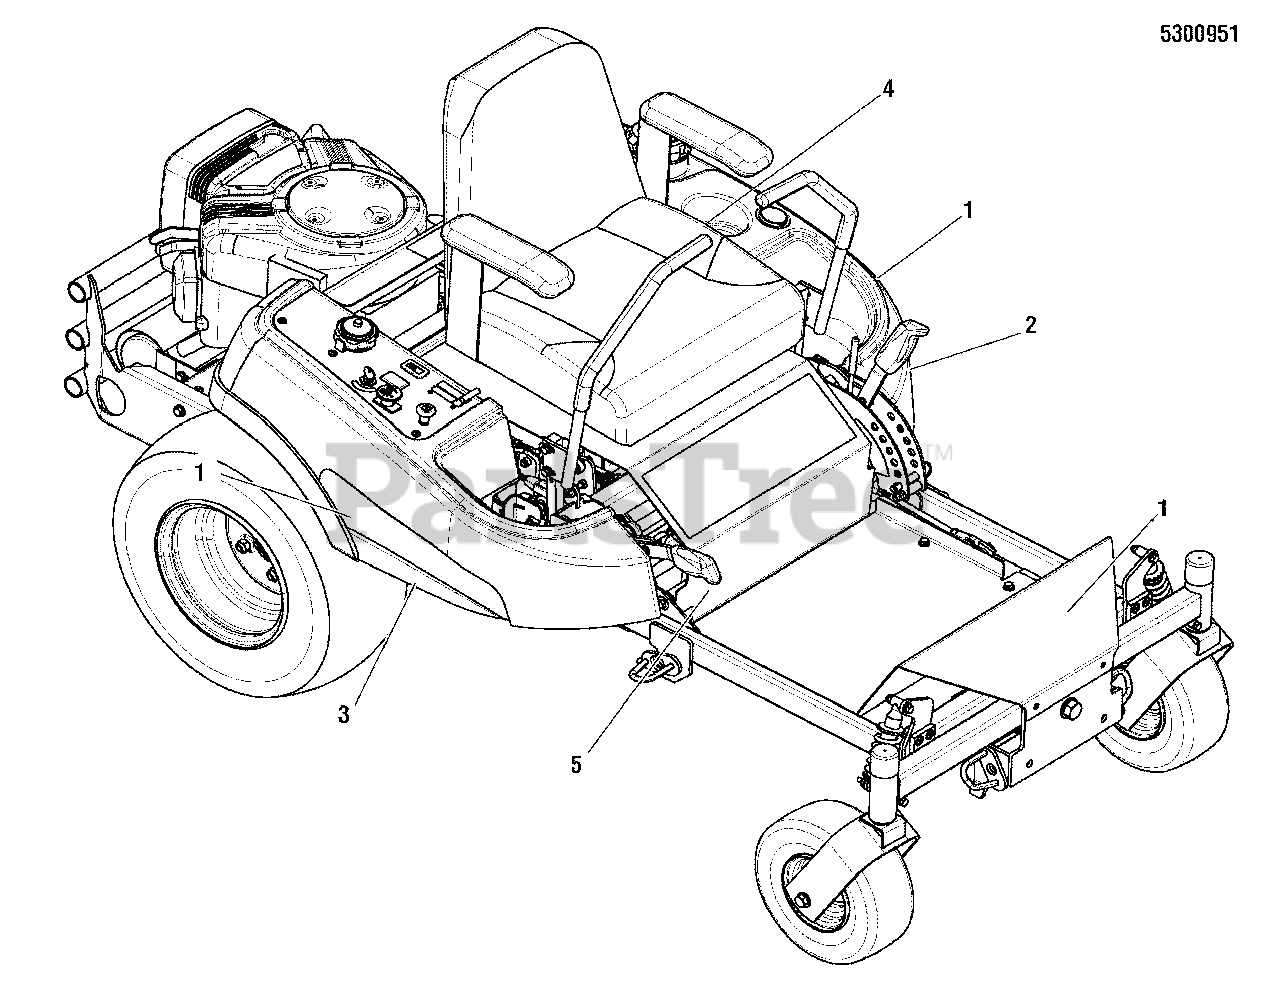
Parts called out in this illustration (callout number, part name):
1	DECAL, Simplicity, Silver & Blue, w/Icon
2	DECAL, Stripe, LH, Simplicity
3	DECAL, Stripe, RH, Simplicity
4	DECAL, Touch Up Paint, Simplicity
5	DECAL, ZT3000 24HP, SMI
